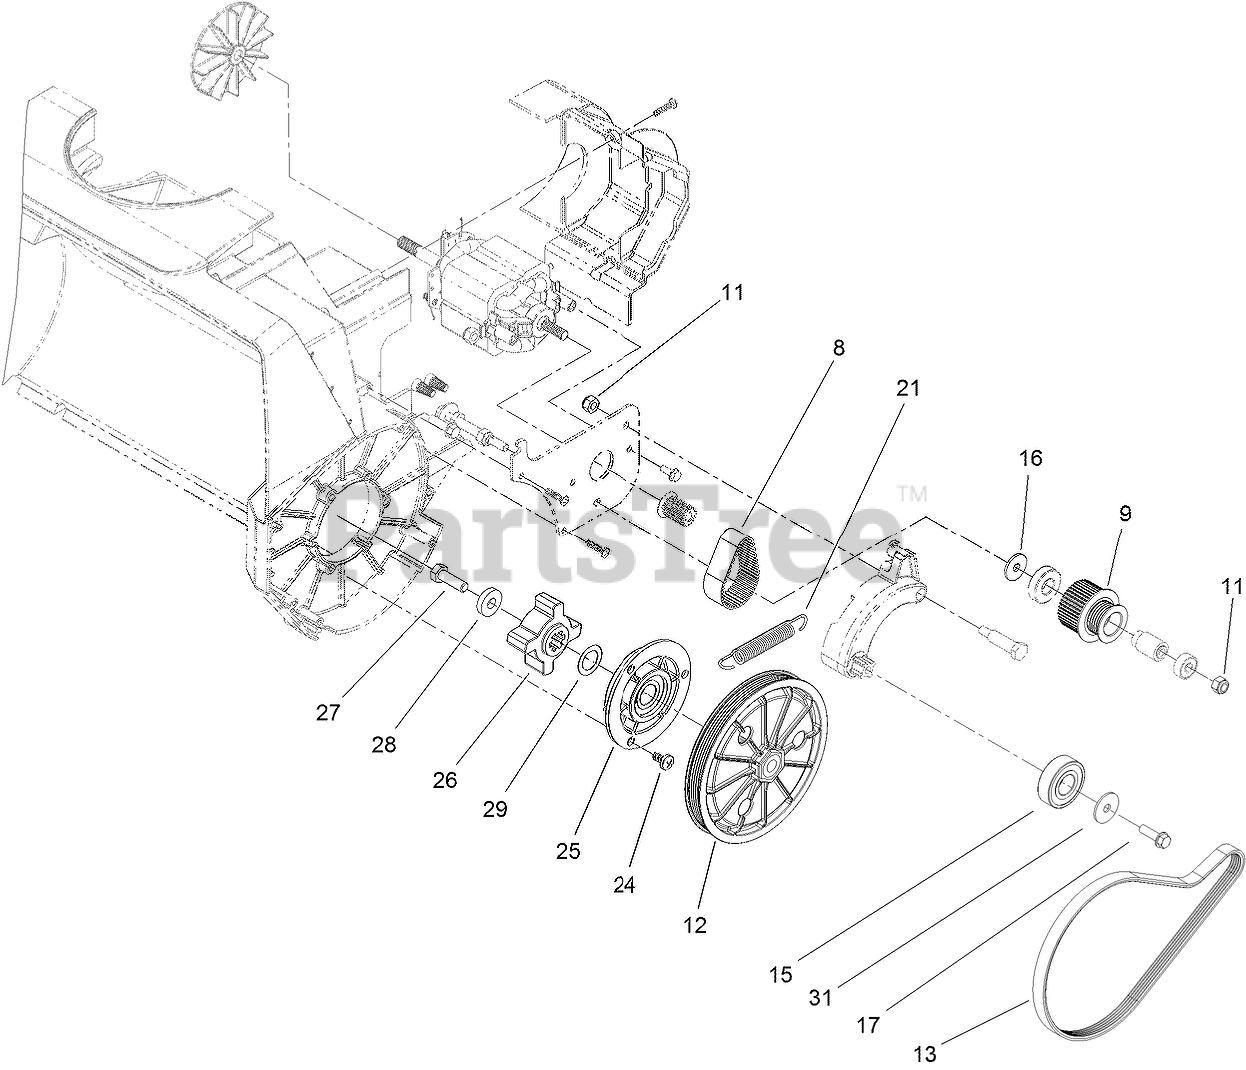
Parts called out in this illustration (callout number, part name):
8	BELT-PULLEY, IDLER/DRIVER
9	IDLER PULLEY ASM
11	NUT-HEX
12	PULLEY ASM
13	BELT-DRIVE
15	BEARING-BALL
16	WASHER-PLAIN
17	SCREW-PLASTITE, HWH
21	SPRING-IDLER
24	SCREW-SEAT, SWITCH
25	PILLOW BLOCK ASM
26	COUPLER-PULLEY
27	SCREW-HH
28	SPACER
29	WASHER-PLAIN
31	WASHER-FLAT
